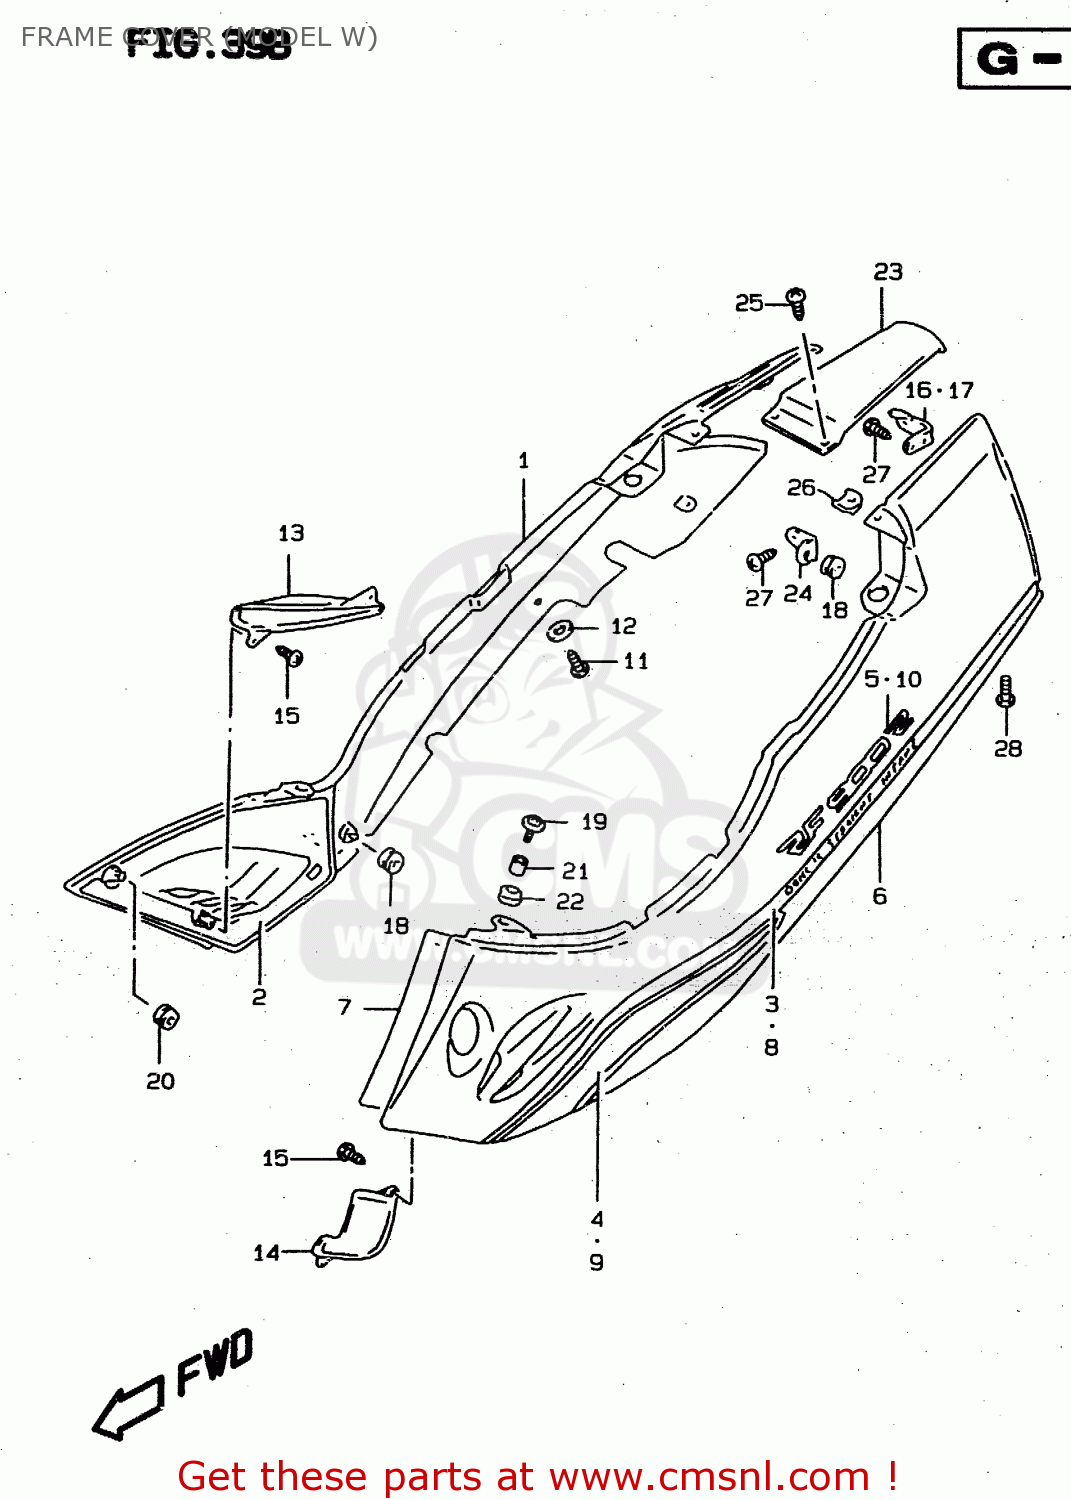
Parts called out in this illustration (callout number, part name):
1	COVER ASSY,FRAME,R(BLACK)
2	SHIELD,FRAME COVER HEAT
3	TAPE SET,FRAME COVER S
4	TAPE, RH
5	EMBLEM
6	COVER, FRAME LH (MAROON)
7	SHIELD,FRAME COVER HEAT,L
8	TAPE SET,FRAME COVER STRIPE,L
9	TAPE, LH
10	EMBLEM
11	SCREW 5X12
12	WASHER(5.2X14X1.5)
13	COVER,INNER,RIGHT
14	COVER,INNER,L
15	SCREW
16	BRACKET,FRAME COVER,R
17	BRACKET,FRAME COVER,L
18	CUSHION
19	BOLT(6X25)
20	CUSHION,FRAME COVER FR
21	SPACER(6.5X9X11)
22	CUSHION
23	COVER,FRAME CTR
24	BRACKET,RR COMBINATION LAMP
25	SCREW 5X12
26	NUT
27	SCREW
28	SCREW
